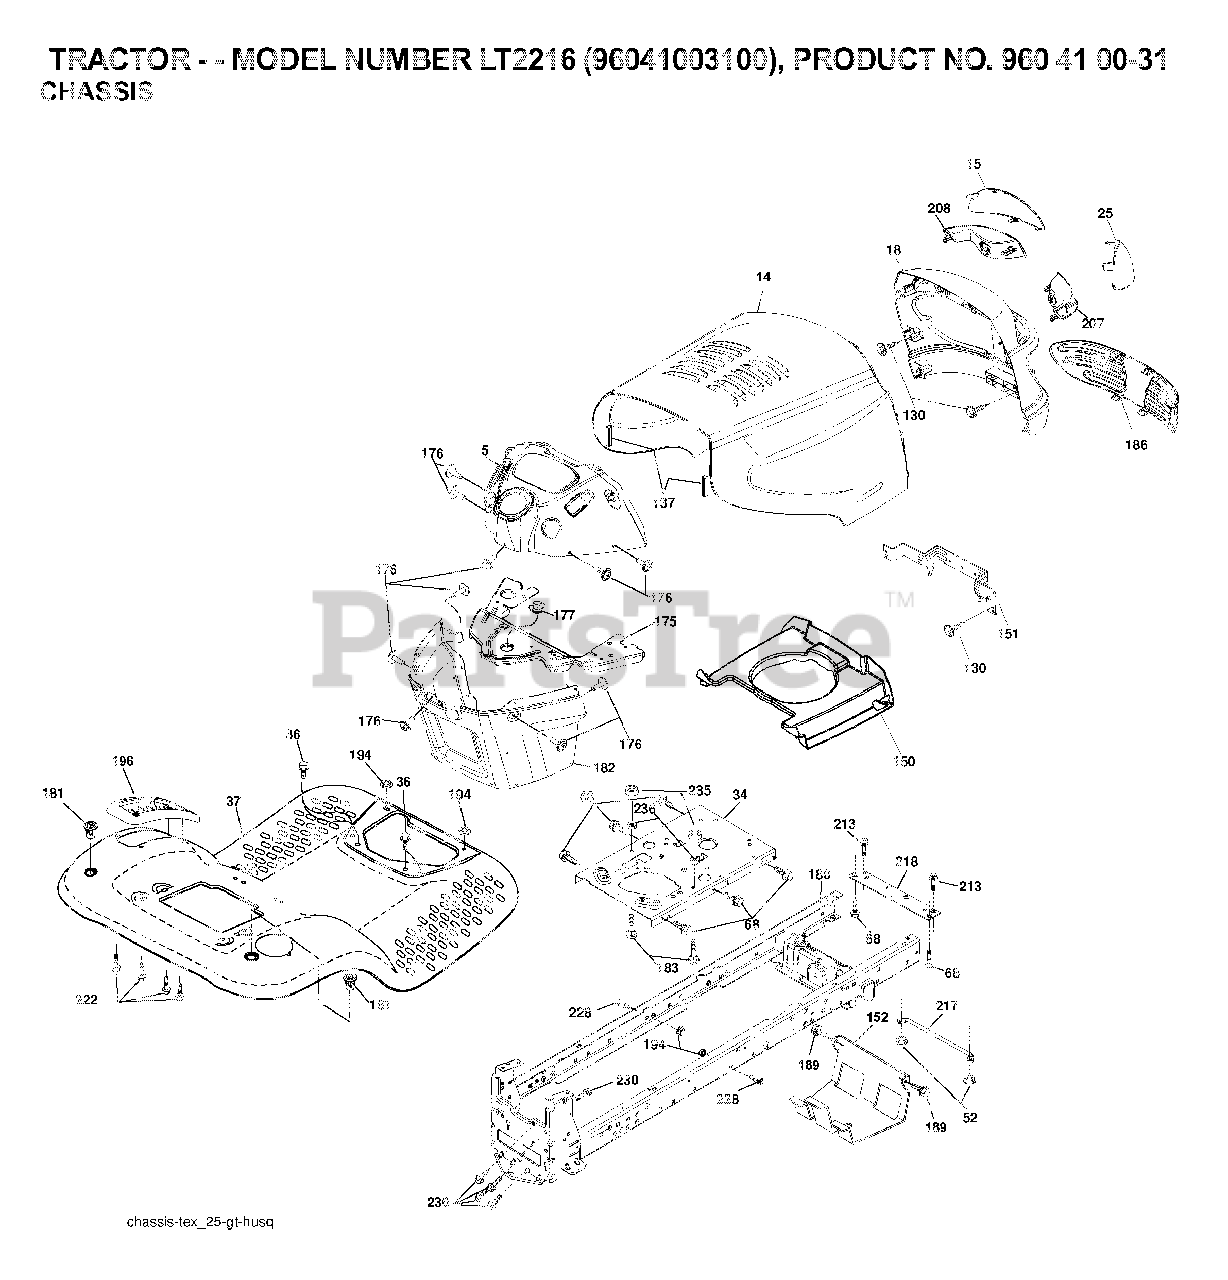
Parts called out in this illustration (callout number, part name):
34	PLATE.ENGINE.WELDED.CHASSIS
36	SCREW 3/8-16X3/4
52	LOCKNUT
130	SCREW
137	BUMPER.HOOD.LARGE.1.75"
151	BRACKET PIVOT
152	SHIELD BROWNING
175	CROSSMEMBER.LT
176	SCREW.#10-24X5/8.RN.QU
177	BUSHING STEERING
180	CHASSIS
181	FEND/FTRST.PCH.CPH.NFW
182	DASH.LOWER.LT.CCS
183	BOLT.5/16-18X1-1/4 FULL.THREAD
189	SCREW
191	INSERT REFLECTIVE
194	NUT LOCK HEX FLANGE 5/16-18
196	CONSOLE.ASM.DECK.LIFT.TLT.BLAC
207	BEZEL GRILL RH
208	BEZEL GRILL LH
213	BOLT
217	ROD PIVOT CHASSIS/HOOD
218	X-PIECE.HOOD.STOP.NON/
222	SCREW.1/4-20X5/8
228	STUD.FASTNER.W/ANTI-ROTATE
230	SHOULDER BOLT 5/16-18TT
235	SPACER FENDER
236	NUT.CENTERLOCK.5/16-
